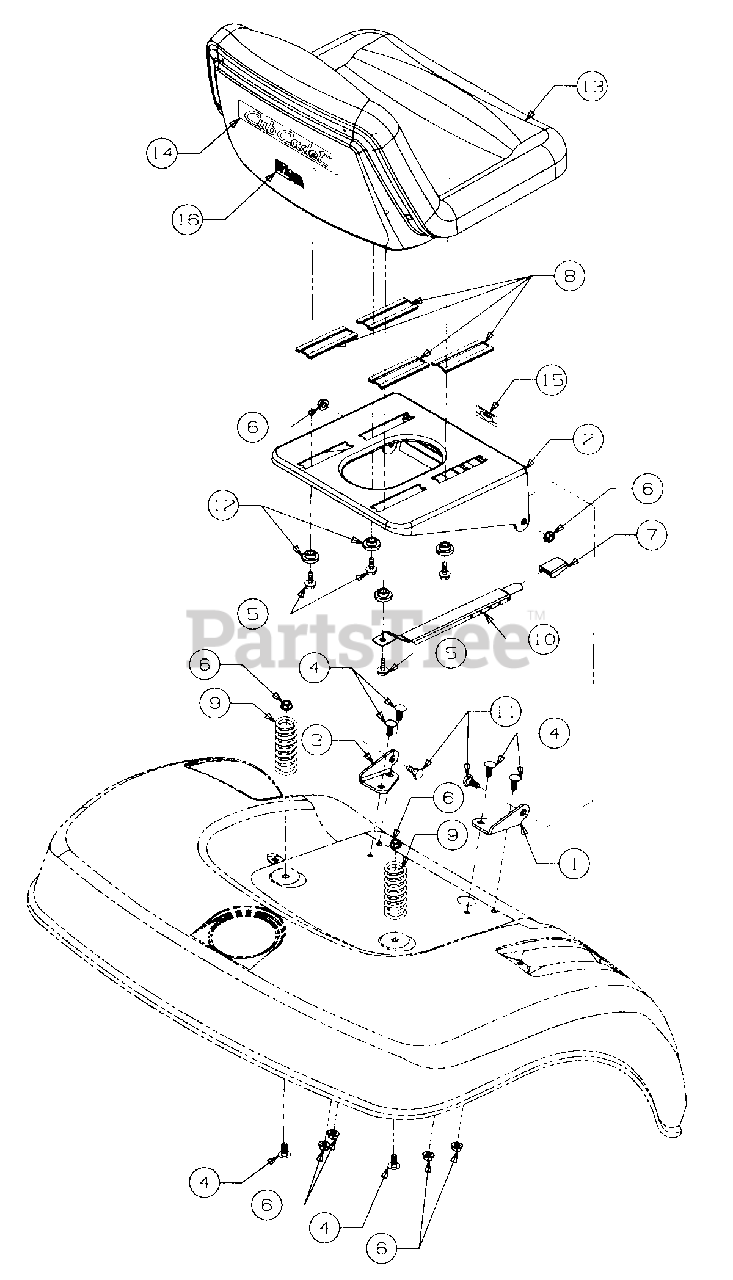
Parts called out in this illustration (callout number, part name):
5	Screw, Hex Wash Sf-Tapp 5/16-18 x .75 Lg
6	Nut, Hex Flange Top Lock 5/16-18
7	Knob, Seat Adjuster
8	Slide, Seat
9	Spring, Compression 1.90 x 2.4 Lg
10	Adjuster, Seat
11	Bolt, Shoulder
12	Spacer, Shoulder
13	Seat, Medium Back
14	Graphic, Seat Back Script
15	Graphic, Seat Adjuster
16	Graphic, Made in USA
